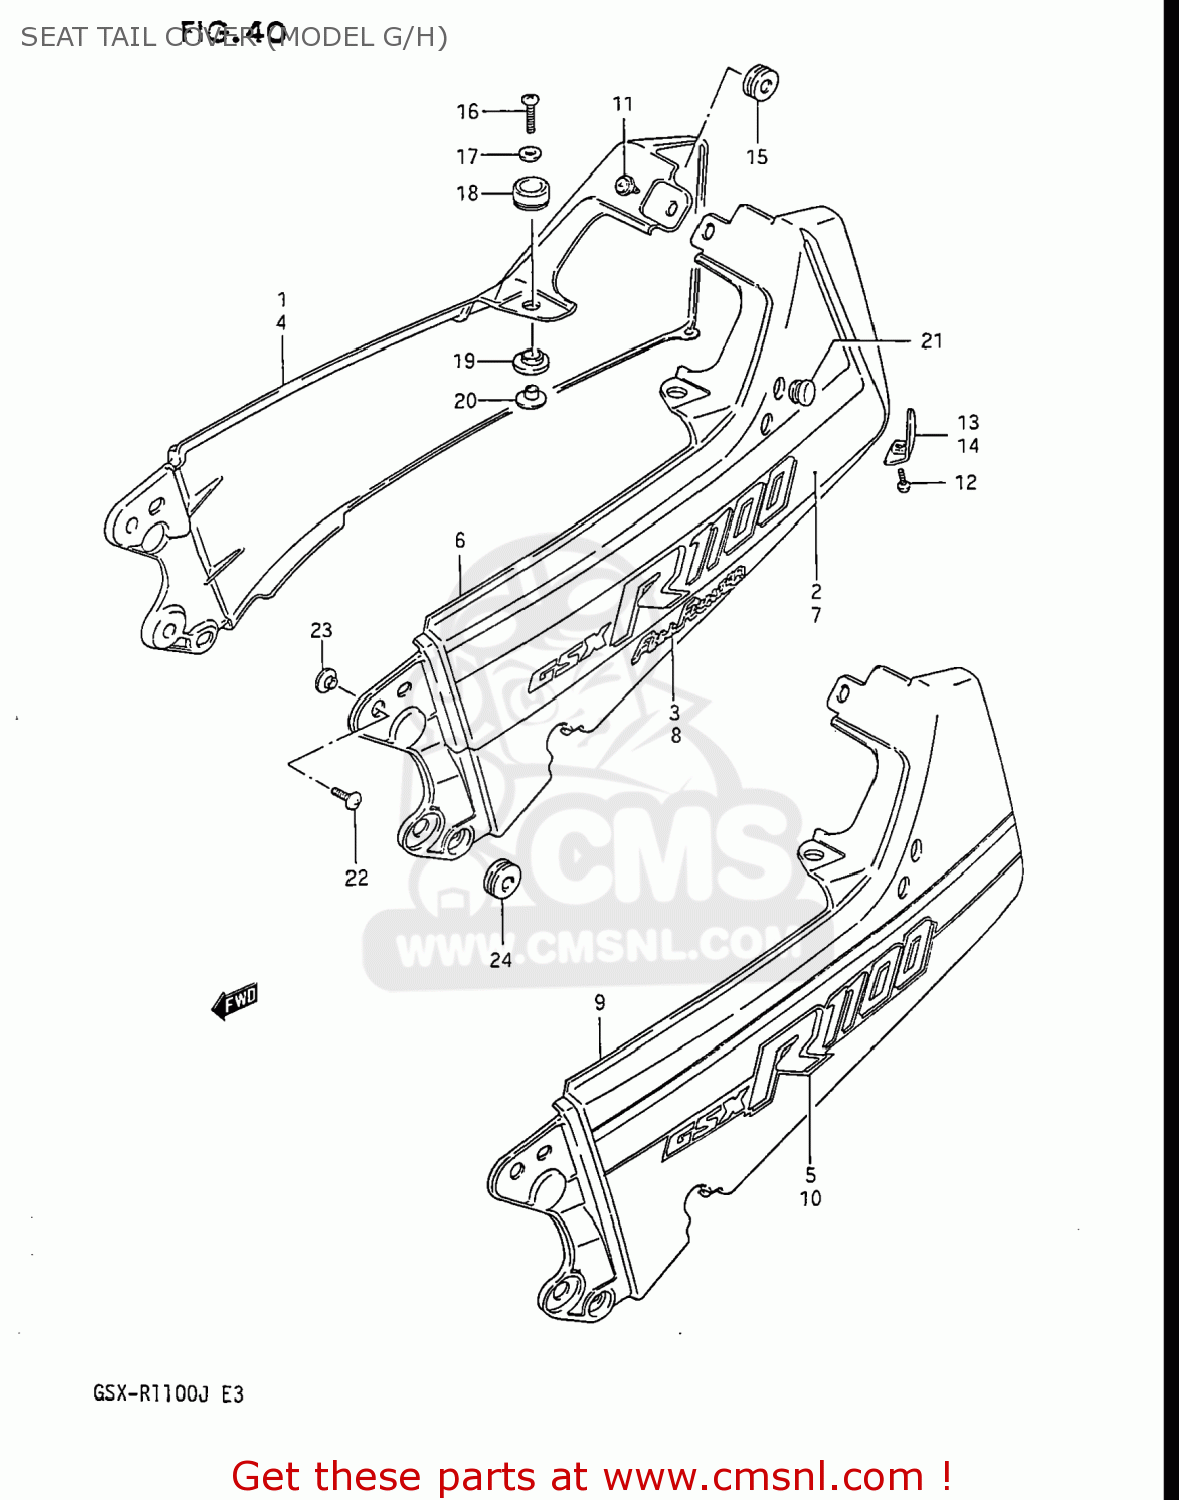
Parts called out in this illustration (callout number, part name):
1	COVER,SEAT TAIL
2	TAPE SET,SEAT TAIL COVER
3	EMBLEM
4	COVER COMP,SEAT TAIL
5	TAPE SET,SEAT TAIL COVER
6	COVER,SEAT TAIL
7	TAPE SET,SEAT TAIL COVER
8	EMBLEM
9	COVER,SEAT TAIL
10	TAPE SET,SEAT TAIL COVER
11	CLIP
12	SCREW
13	PLATE,SEAT TAIL COVER,RH
14	PLATE,SEAT TAIL COVER,L
15	CUSHION
16	SCREW
17	WASHER
18	CUSHION,TAIL COVER UPR
19	CUSHION,TAIL COVER LWR
20	SPACER,SEAT TAIL COVER
21	CAP,SEAT TAIL COVER
22	SCREW
23	WASHER
24	CUSHION
